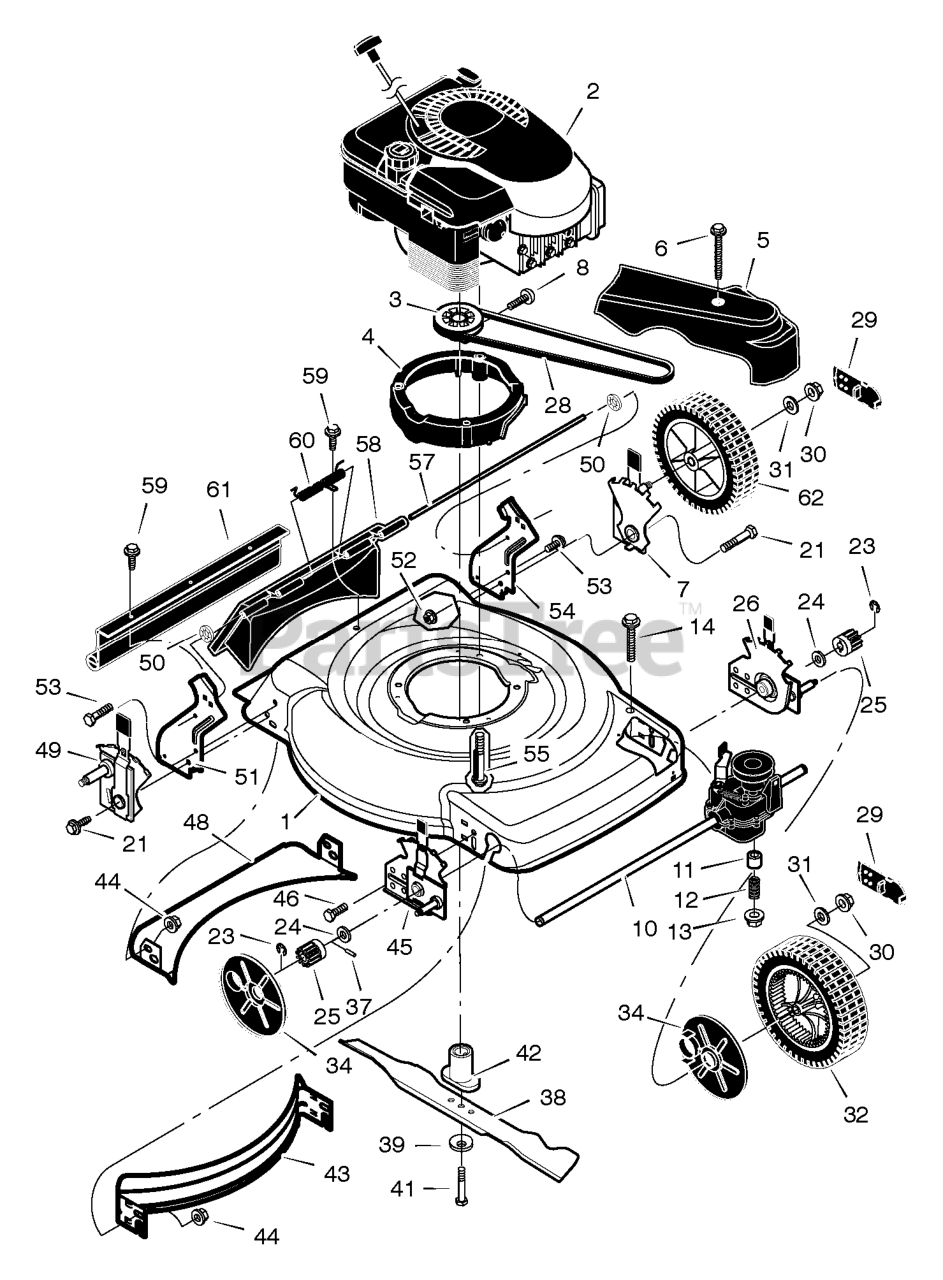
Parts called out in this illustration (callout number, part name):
1	Housing
2	Engine *
3	Pulley, Drive
4	Spacer, Engine
5	Cover, Belt (Black)
6	Screw
7	Adjuster, Left Rear Height
8	Screw
10	Transmission *
12	Spring, Compression
13	Nut
14	Bolt
21	Bolt
25	Gear, Pinion
26	Adjuster, Left Front Height
29	Cap, Hub
30	Nut, Flange
31	Washer
32	Wheel & Tire, Front
34	Cover, Dust
37	Pin, Drive
38	Blade
39	Washer, Belleville
42	Adapter, Blade
43	Baffle, Front
44	Nut, Flange
45	Adjuster, Right Front Height
46	Bolt
48	Baffle, Rear
49	Adjuster, Right Rear Height
50	Retainer, Push t
51	Bracket, Right Handle
52	Nut, Flange
53	Bolt
54	Bracket, Left Handle
55	Bolt, Engine
57	Rod, Pivot t
58	Door, Rear (Black)
60	Spring
61	Guard, Rear
62	Wheel & Tire, Rear
